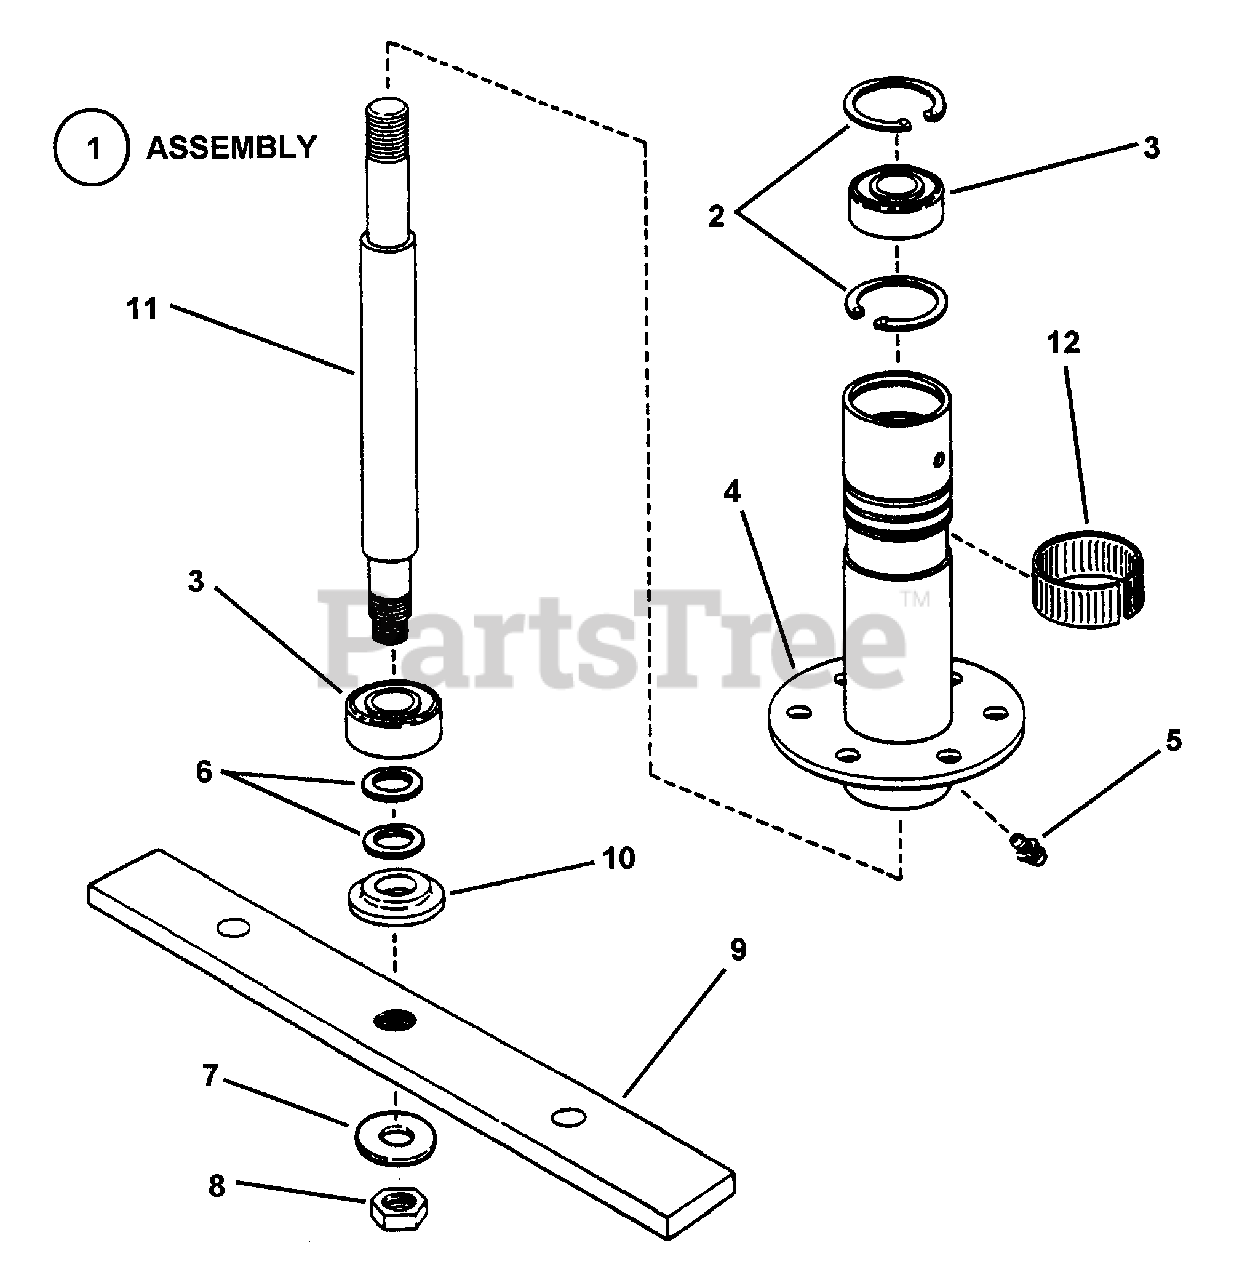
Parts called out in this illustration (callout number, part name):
1	ASSEMBLY, Spindle Housing
2	RING, 1.85" Internal Retaining
3	BEARING, Spindle
4	WELDMENT, Spindle Housing
5	FITTING, Lube (Press fit for .187 hole-no ball)
6	WASHER, 49/64" Shim
7	SPACER, Blade Centering
8	NUT, 5/8-18 Hex Center Jam Lock
9	HOLDER, Blade
10	WASHER, Spindle
11	SPINDLE, Shaft (10.237" Long)
12	RING, 2" Tolerance
